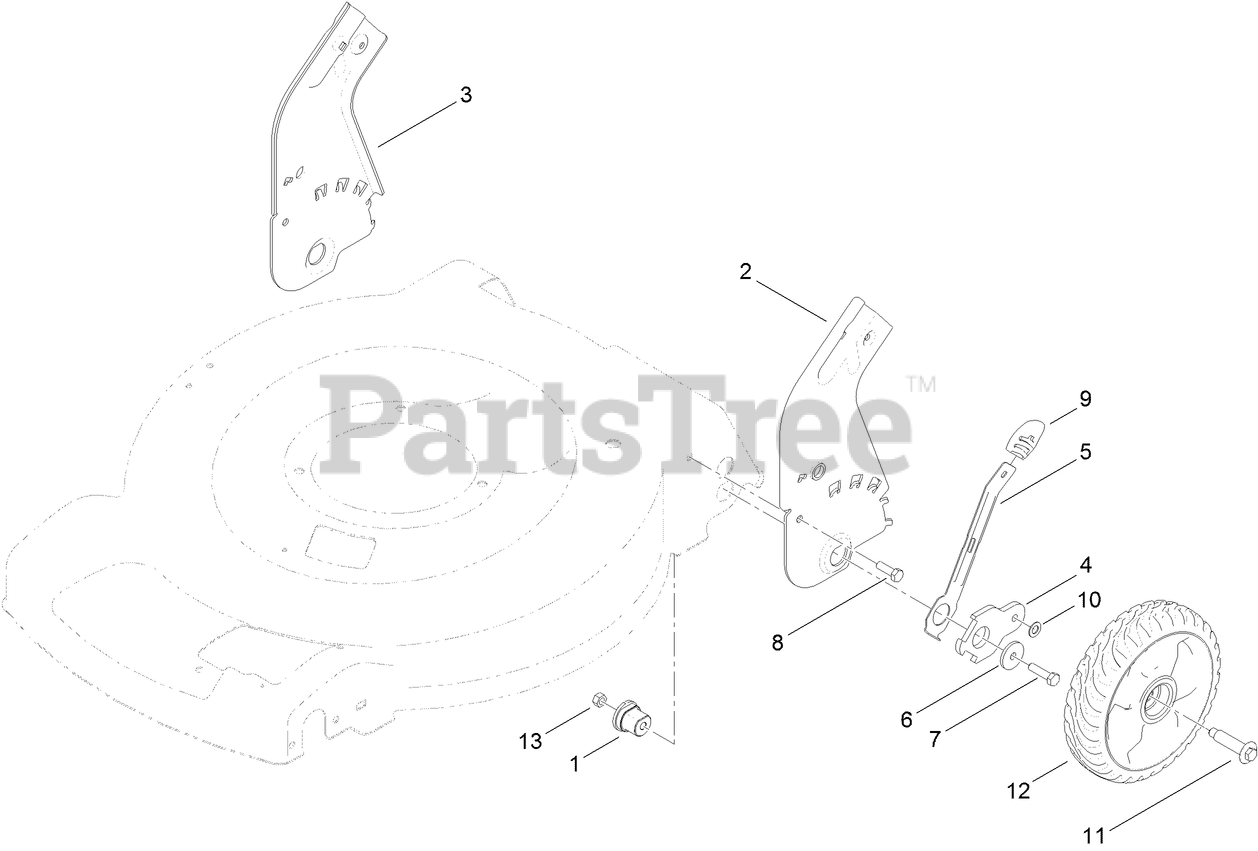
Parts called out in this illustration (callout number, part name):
1	BUSHING-MOUNT, HOC
2	PLATE-HOC, REAR (LH)
3	PLATE-HOC, REAR (RH)
4	ARM-PIVOT, REAR
5	ARM-SPRING, REAR
6	Washer-Flat
7	SCREW-HH
8	SCREW-HH
9	Knob-Lever, HOC
10	WASHER
11	BOLT-SHOULDER
12	8 INCH WHEEL ASM
13	NUT-LOCK, NI
